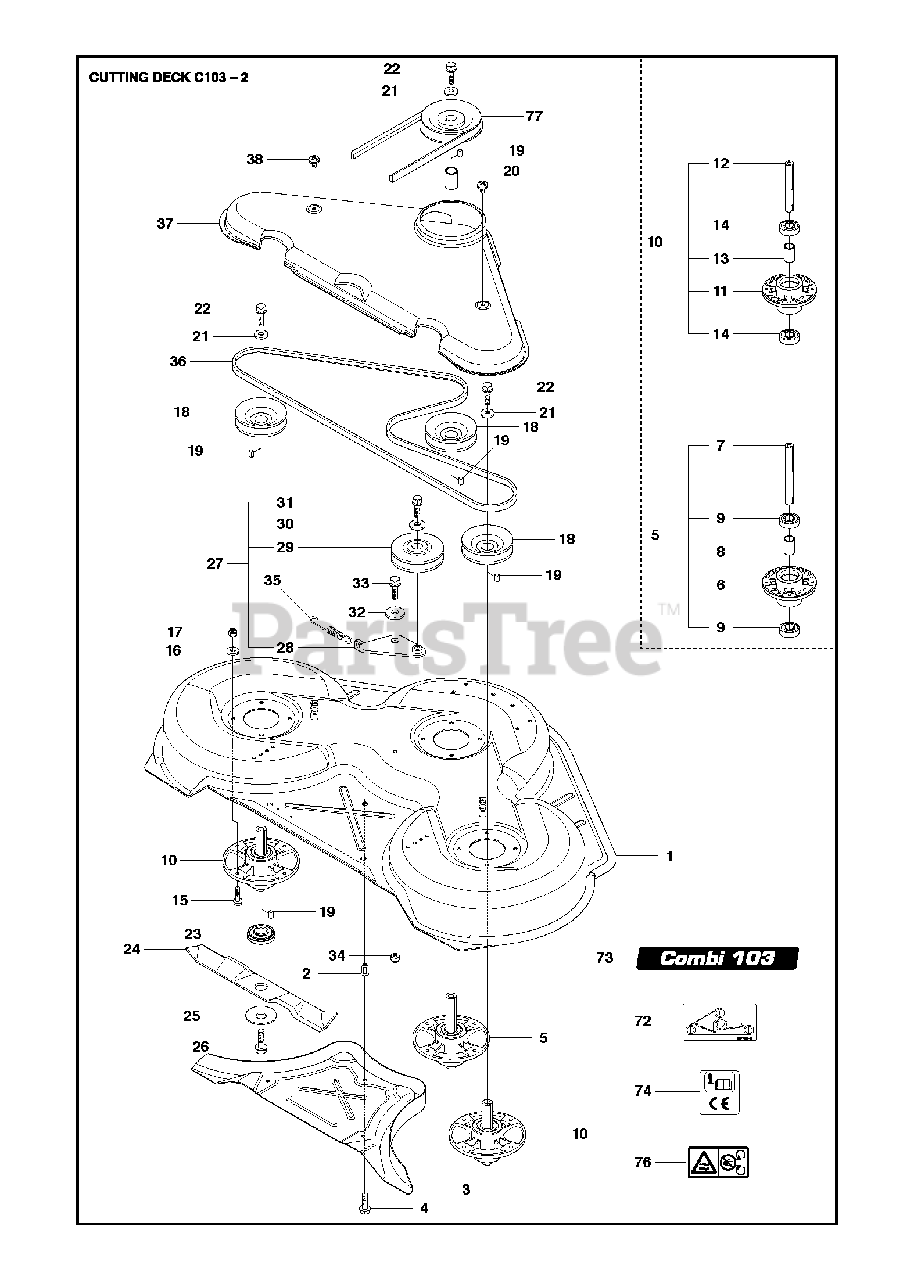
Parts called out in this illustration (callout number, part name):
6	BEARING HOUSING
8	SPACING SLEEVE
9	BEARING
10	BLADE HOUSING ASSY
11	BEARING HOUSING
12	SHAFT
13	SPACING SLEEVE
14	BEARING
16	WASHER BRB 8.4X17
17	LOCKNUT M8
20	SPACING SLEEVE
25	WASHER
27	BELT TENSIONER ASSY
28	BELT TENSIONING ARM
29	PULLEY
30	SPACER
31	BOLT
32	WASHER
34	LOCKNUT M8
36	BELT
